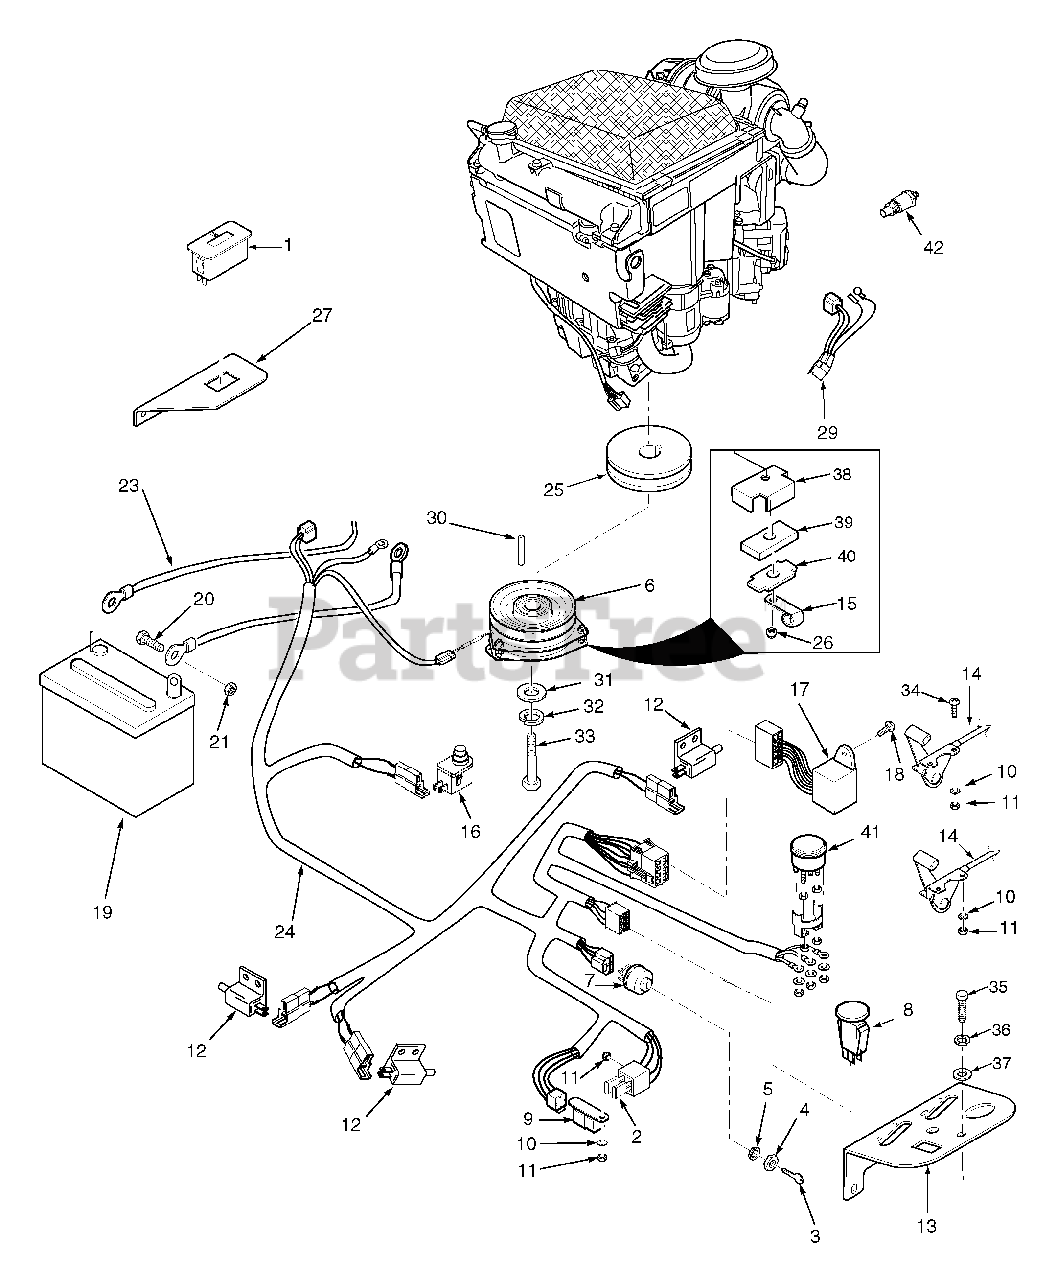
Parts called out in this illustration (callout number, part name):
1	Hourmeter
2	Fuse, 20 amp
3	Key, Ignition
4	Nut, Hex 5/8-32
5	Lockwasher, 5/8" Internal
6	Electric PTO Clutch GT3.5
7	Switch, Ignition
8	Switch, PTO
9	Relay
10	Lock Washer, #10 External Tooth
11	Nut, Hex #10-32
12	Switch, N/O
13	Panel, Instrument
14	Choke & Throttle Control - Kawasaki
16	Switch, Seat
17	Module, Interlock
18	Screw, #10-32 x .5" Phillips Head
19	Battery
20	Bolt, Hex Head 1/4-20 x .5"
21	Nut, Hex 1/4-20
22	Cable, Battery Black (negative)
23	Cable, Battery Red (positive)
24	Wiring Harness, Main
25	Pulley, 5.45 OD x 1.125 Bore
26	Nut, Elastic Stop 5/16-18 Key
27	Mounting Bracket, Hour Meter
28	Screw, #10-32 x 1.5" Phillips Head
29	Adaptor, Wiring Harness
30	Key, 1/4 x 1/4 x 3-1/4"
31	Flatwasher, 7/16-.469 x 1-3/4" x 1/4"
32	Lockwasher, 7/16"
33	Bolt, Hex Head 7/16-20 x 2-1/4" UNF
34	Screw, #10-32 x 3/4"
35	Bolt, Hex Head 5/16-18 x 3/4"
36	Lockwasher, 5/16
37	Flatwasher, 5/16-.375 x .875 x .083
38	Backing Plate
39	Rubber Pad, Clutch Stop
40	Plate, Backing
41	Water Temp. Gauge
42	Sender Unit, Water Temp
